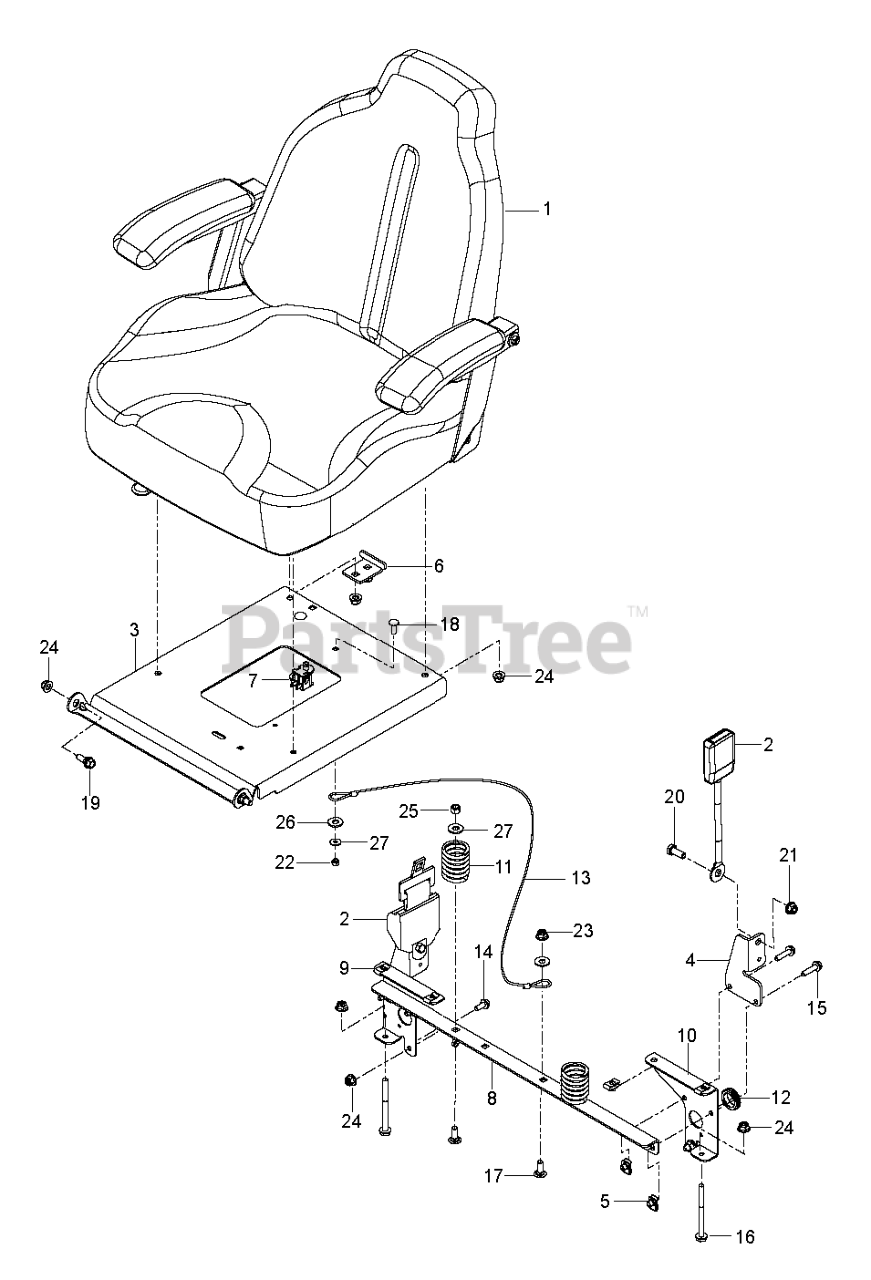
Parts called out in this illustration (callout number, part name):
1	SEAT.907.VINYL.HUSQVARNA
2	KIT.SEAT.MOUNT.W/DECAL
3	MOUNT, SEAT BELT, BLACK
4	4"SINGLE LOCK TRACK SET W/HDWR
5	STOP, SEAT - BLACK
6	SEAT SWITCH
7	SUPPORT, SEAT
8	SUPPORT, RT, BLK
9	SUPPORT, LT, BLK
10	SPRING, SEAT
11	RUBBER GROMMET
12	SEAT LANYARD
13	SEAT BELT, RETRACTABLE
14	HHFS 5/16-18 X 3/4
15	HHFS 5/16-18 X 1.25 TPBLT GD 5
16	HHFS 5/16-18 X 3 3/4
17	RHSNB 3/8C X 1
18	RHSNB 1/4C X 3/4
19	SB 5/16-18 HEX HD GD5, BLK ZN
20	SCREW 7/16-20 X 1 HHB GR5
21	NUT HEX 7/16F LOCK RP
22	NUT 5/16 NYLOC
23	NUT.1/4-20.HEX.NYLOC.ZD
24	NUT 3/8-16 HEX FLG NYLOC ZD
25	5/16-18 NYLOC FLANGE NUT
26	NUT 3/8-16 NYLOC
27	WASHER 1/4 FLAT
